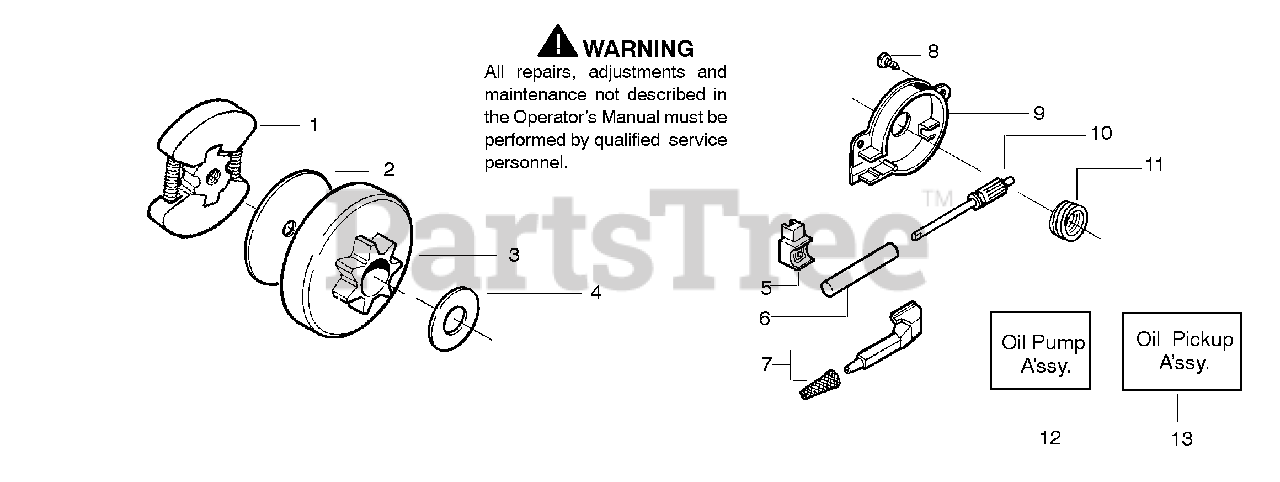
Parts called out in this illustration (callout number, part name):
1	Assy-Clutch
2	Washer-Clutch
3	Assy-Clutch Drum w/Bearing (3/8 x 6 spur)
4	Washer-Thrust
5	Seal-Oil
6	Barrel-Oil Pump
7	Assy-Oil Pick-Up and Screen
9	Housing-Oil Pump
10	Assy-Plunger & Gear
11	Worm-Oil Pump
12	Assy-Oil Pump
13	Assy-Oil Pickup
